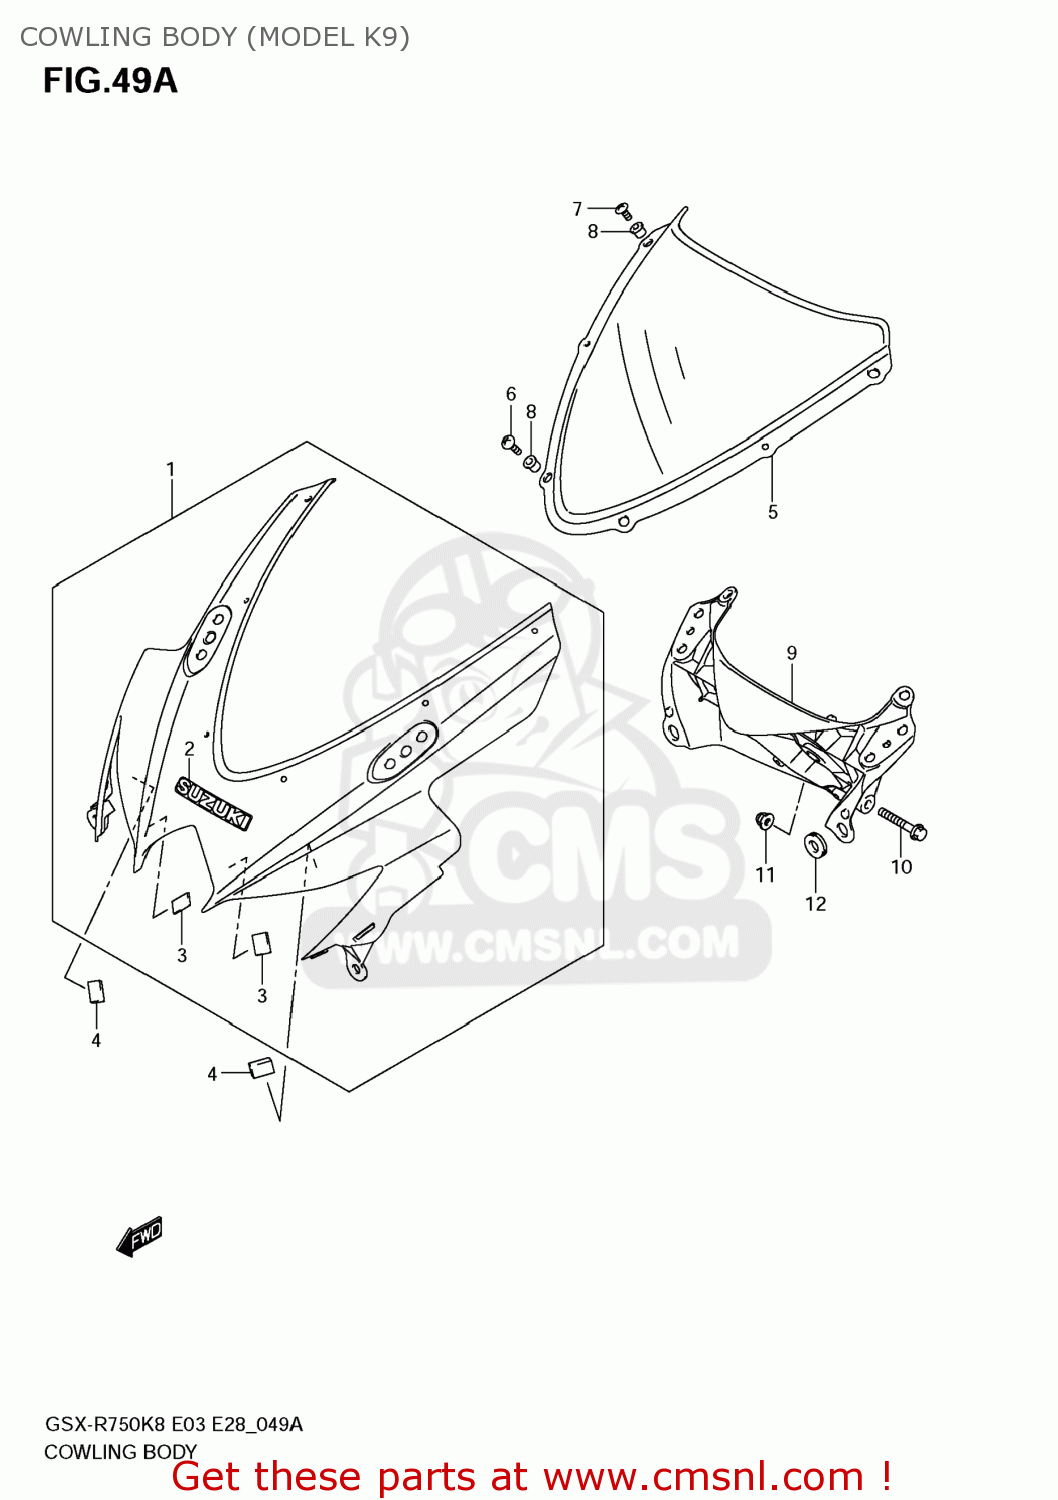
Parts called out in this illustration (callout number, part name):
1	BODY ASSY,COWLING
2	EMBLEM,SUZUKI
3	FASTENER,COWLING
4	CUSHION,BODY COWLING
5	WINDSCREEN
6	SCREW(5X18)
7	SCREW(5X15)
8	NUT
9	BRACE,COWLING
10	BOLT
11	NUT
12	CUSHION
